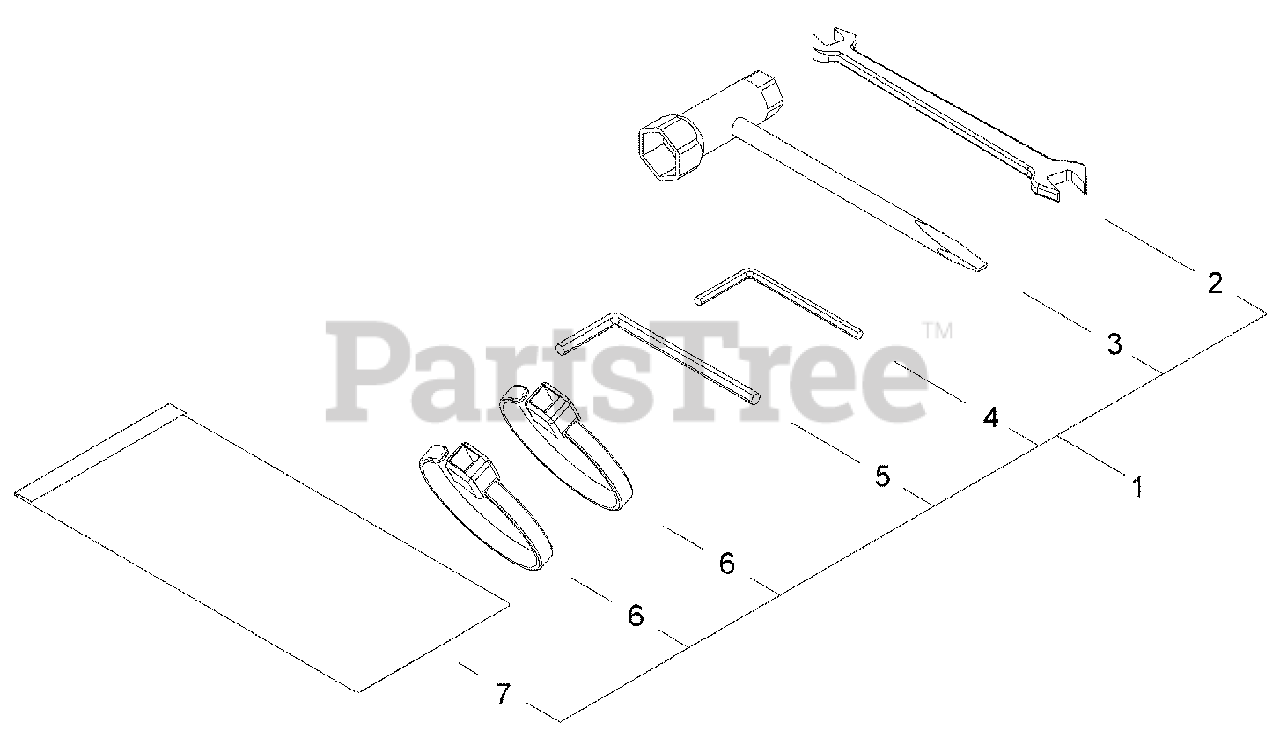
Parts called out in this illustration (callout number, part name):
1	TOOL KIT
2	SPANNER - 8X10mm
3	T-WRENCH - 13X16mm
4	HEX KEY - 4mm
5	HEX KEY - 6mm
6	BAND
7	BAG, TOOL
